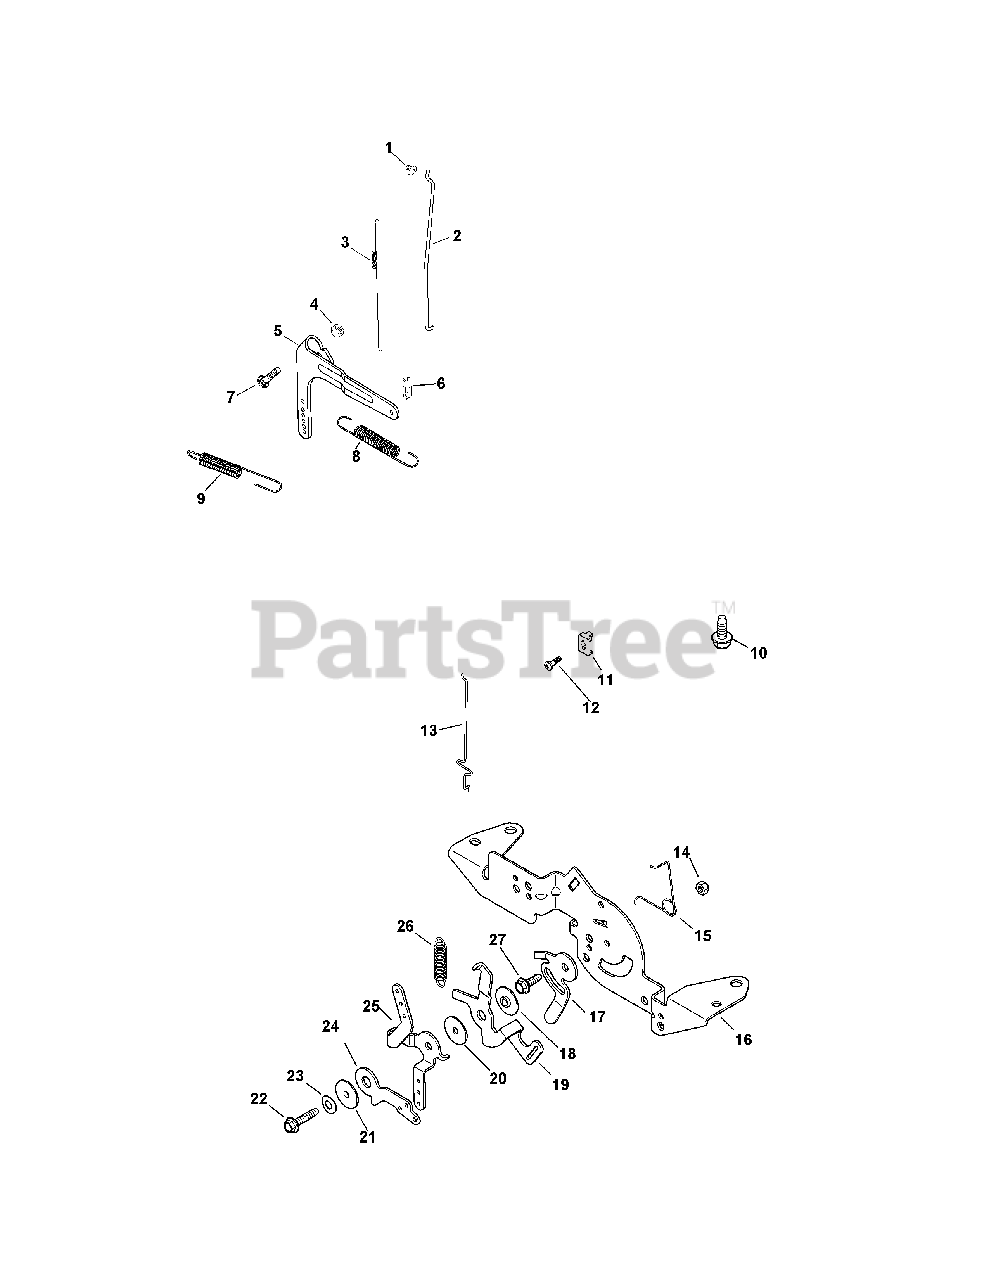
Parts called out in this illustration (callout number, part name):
1	Bushing, Linkage Retaining
2	Linkage, Throttle
3	Spring, Linkage
4	Nut, Flg M6X1.0
5	Lever, Governor
6	Bushing, Throttle Linkage
7	Bolt, Rd Hd Sq Neck M6X1.0X25
8	Spring, Governed Idle
9	Spring, Governor
10	Screw, Flg Thd Fr! M M6X1.0X16
11	Clamp, Cable
12	Screw, Lbd Thd Frm M5X0.8X16
13	Linkage, Choke
14	Nut, Lock M5X.8
15	Spring, Choke Return
16	Bracket, Control
17	Lever, Speed Setting
18	Spacer, Control Assembly
19	Lever, Governor Spring
20	Washer, Flat 5.5 Mm
21	Spacer, Control Assembly
22	Screw,Thread Formng M5X0.8X25Mm
23	Washer, Spring 1/4''
24	Lever, Choke
25	Lever, Speed Control
26	Spring, Speed Control
27	Screw, Flg Thd Frm M5X0.8X16
